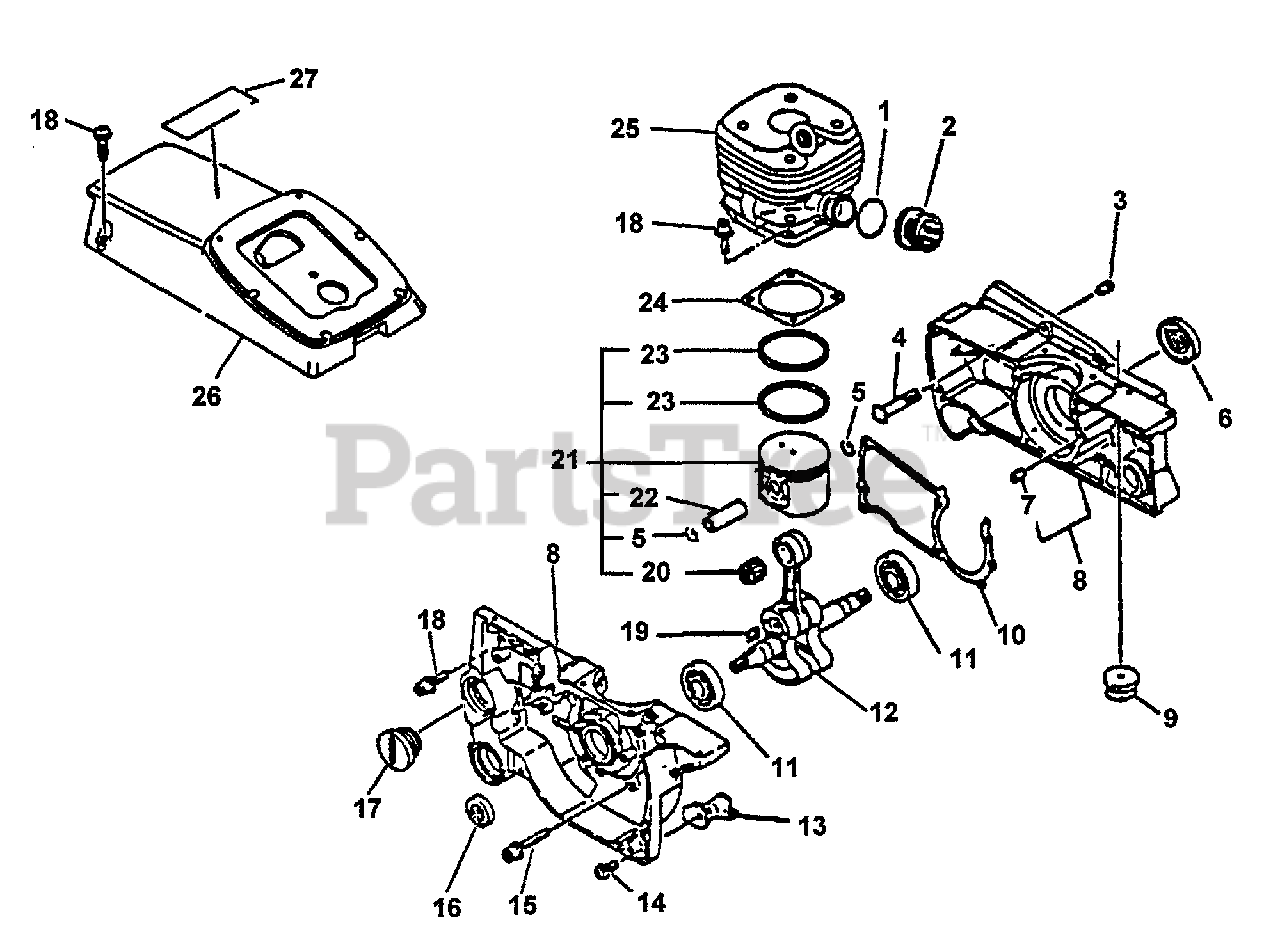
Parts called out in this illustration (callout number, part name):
2	BELLOWS, INTAKE
3	VENT, TANK
4	STUD, GUIDE BAR
5	RING, RETAINING
6	SEAL, OIL
7	PIN - LOCATING
8	CRANKCASE KIT
9	CUSHION - A
10	GASKET, CRANKCASE
11	BEARING, BALL - 6202
12	CRANKSHAFT ASSY
14	SCREW - 5X14
15	SCREW - 5X35
16	SEAL, OIL
17	PLUG
18	SCREW - 5X20
20	BEARING, NEEDLE
21	PISTON KIT
22	PIN, PISTON
23	RING, PISTON
24	GASKET, CYLINDER
25	CYLINDER KIT
26	COVER, ENGINE
27	LABEL - CAUTION
